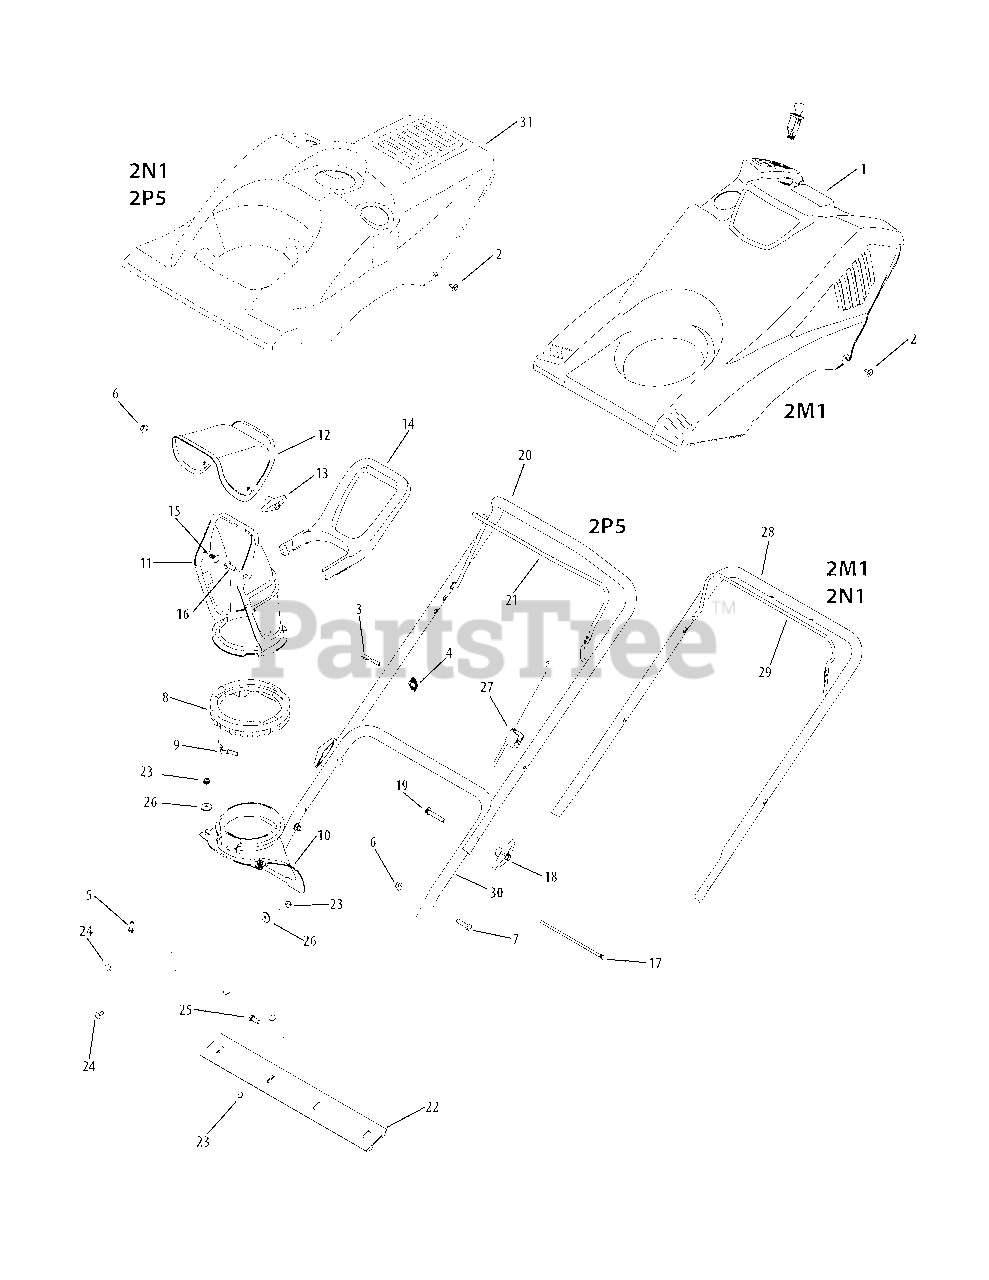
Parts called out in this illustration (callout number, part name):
1	Shroud Ass’y (Model 2M1)
2	Hex Wash B-Tapp Scr #10 x .62" Lg.
3	Eyebolt 1/4-20
4	Handle Knob Assembly
5	Hex Tapp Scr 1/4 x .75" Lg.
6	Flange Locknut 5/16-18 Gr. F, Nylon
7	Hex Flg. Screw 5/16-18 x 1.25
8	Lower Chute Ring
9	Chute Adjustment Spring
10	Chute Adapter 5" Dia
11	Lower Chute 5" Dia
12	Upper Chute
13	Handle Knob Assembly
14	Chute Handle
15	Carriage Bolt 5/16-18 x .75
16	Carriage Screw 5/16-18 x 1.0
17	Cable Tie
18	Handle Knob Assembly
19	Carriage Bolt 5/16-18 x 2.0 Gr. 5
20	Gullwing Handle
21	Control Bail
22	Shave Plate
23	Hex L-Flanged Nut 1/4-20 Gr. F Nylon
24	Carriage Bolt 1/4-20 x .62
25	Hex Screw 5/16-18 x .75
26	Flat Washer .25 ID x .93 OD x .125
27	Control Cable
28	Upper Handle
29	Control Bail
30	Lower Handle
31	Shroud Ass’y (Mod els 2N1 & 2P5)
